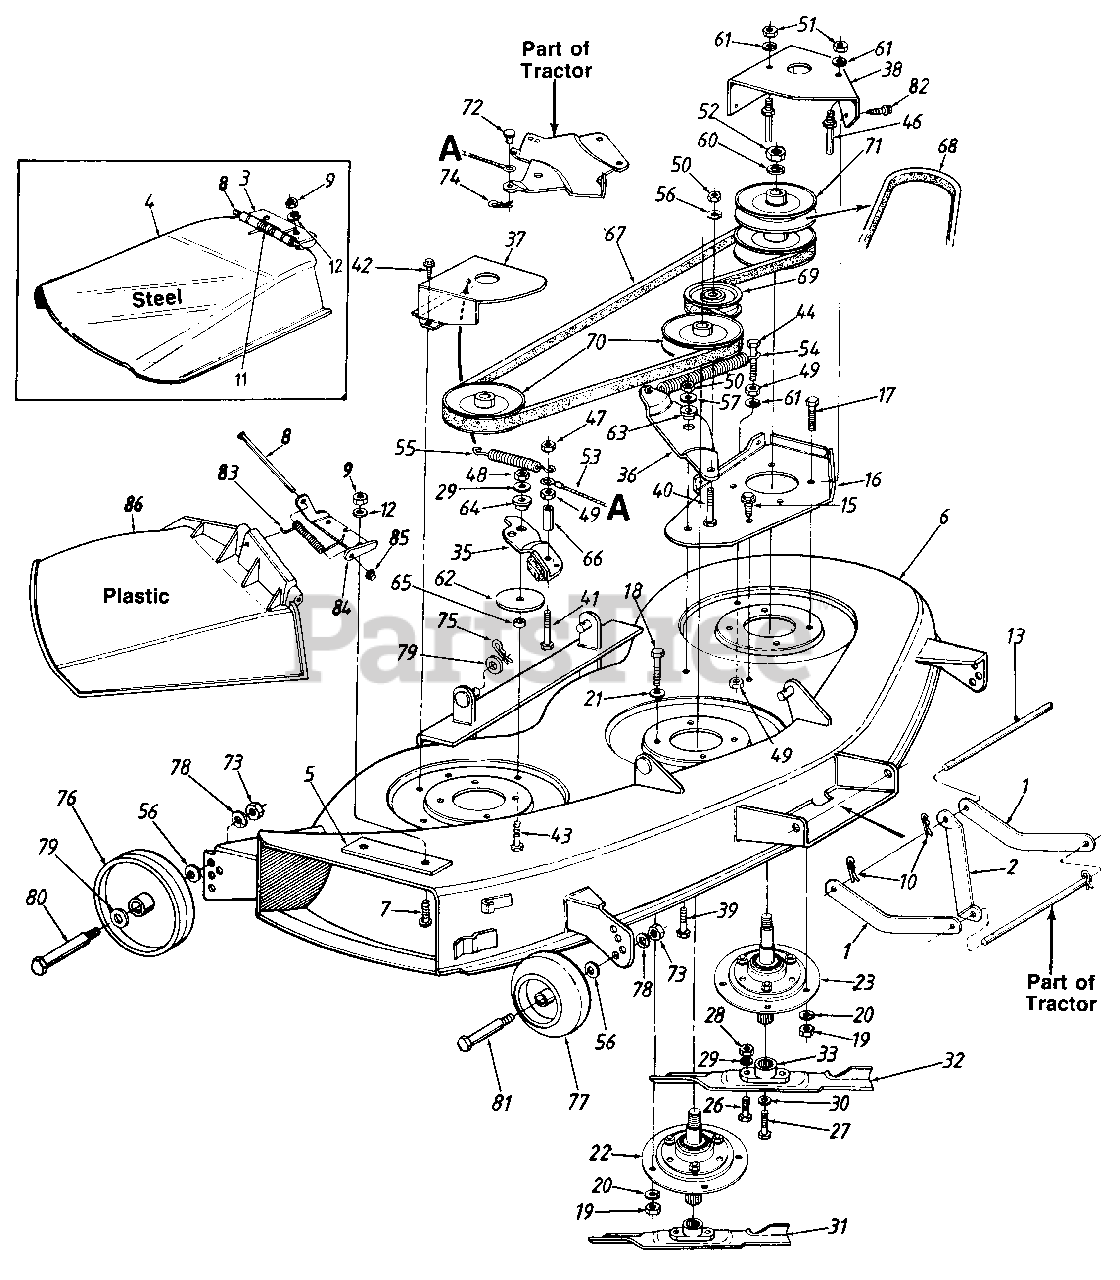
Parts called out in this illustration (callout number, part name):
4	Deck Chute (Steel)
5	Chute Mtg. Plate
6	46" Deck Ass'y.
7	Truss Mach. Scr. 1/4-20 X .751'
8	Hinge Pin
9	Hex Jam Nut 1/4-20 Thd.
10	Int. Cotter Pin
11	Torsion Spring
12	Bell-Wash. 1/4" I.D.
13	Deck Connecting Rod
15	Hex TT-Tap Scr. 5/16-18 x .62"
18	Hex Bolt 5/16-24 x .75" Lg.
19	Hex Nut 5/16-24 Thd.
20	L-Wash. 5/16" I.D.
21	Bell-Wash. 5/16" I.D.
22	Spindle Ass'y.
23	Spindle Ass'y.
26	Hex Bolt 5/16-24 x 1.0" Lg.
27	Hex Cl-Bolt 3/8-24 x .88" Lg.
28	Hex Nut 5/16-24 Thd.
29	L-Wash. 5/16" I.D.
30	L-Wash. 3/8" I.D. H.D.
31	High Lift Blade 14.88" Lg.
32	High Lift Blade 16.28" Lg.
33	Blade Adapter
35	Deck Brake Brkt. Ass'y.
36	Idler Bracket
40	Hex Bolt 3/8-24 x 1.5" Lg.
41	Hex Bolt 1/4-28 X 1.75" Lg.
42	Hex Wash. Hd. Tap-Scr. 1/4-20 X .5" Lg.
43	Hex Bolt 5/16-24 x 1.25" Lg. (Grade 5)
44	Hex Bolt 1/4-28 x 1.5" Lg.
46	Belt Guard Pin 1/4" Dia.
47	Hex Cent. L-Nut 1/4-28 Thd.
48	Hex Nut 5/16-24 Thd.
49	Hex Nut 1/4-28 Thd.
50	Hex Nut 3/8-24 Thd.
51	Hex Nut 1/4-20 Thd.
52	Hex Jam Nut 5/8-18 Thd.
53	Brake Cable Ass'y.
54	Extension Spring 6.17" Lg.
55	Extension Spring 3.97" Lg.
56	Bell-Wash. .38" I.D. x .88" O.D.
57	Bell-Wash. .39" I.D. x 1.13" O.D.
60	Bell-Wash. 518" I.D. x 1.25" O.D.
61	L-Wash. 1/4" I.D.
62	Fl-Wash. 5/16" I.D. x 3" O.D.
63	Shld. Spacer .625" I.D.
64	Shld. Spacer
65	Spacer.34" I.D.
66	Spacer.326" I.D.
67	V-Belt
68	V-Belt
69	Fl-Idler w/Flanges 3.5" O.D.
70	Pulley 5.0" Dia.
71	Pulley 5.0" Dia.
72	Clevis Pin 1/4" Dia. x .53" Lg.
73	Hex Nut 3/8-16 Thd.
74	Intern. Cotter Pin 5/16" Dia.
75	Intern. Cotter Pin 3/8 Dia.
76	Deck Wheel 5" Dia.
77	Deck Wheel w/lnsert 5" Dia.
78	L-Wash. 3/8" I.D.
79	Fl-Wash. .531" I.D.
80	Shoulder Bolt .498" Dia. x 1.64" Lg.
81	Shoulder Bolt
82	Hex Wash. Hd. Tap-Scr. 1/4-20 X .38" Lg.
83	Torsion Spring
84	Hinge Mtg. Brkt.
85	Push Nut
86	Chute Ass'y. Comp. (Plastic)
17258-0648	Deck Belt Cover, 46" Black - TECH GRAY (0648)
17258-0665	COVER:BELT:DECK 46 - YARDMAN GREEN (0665)
